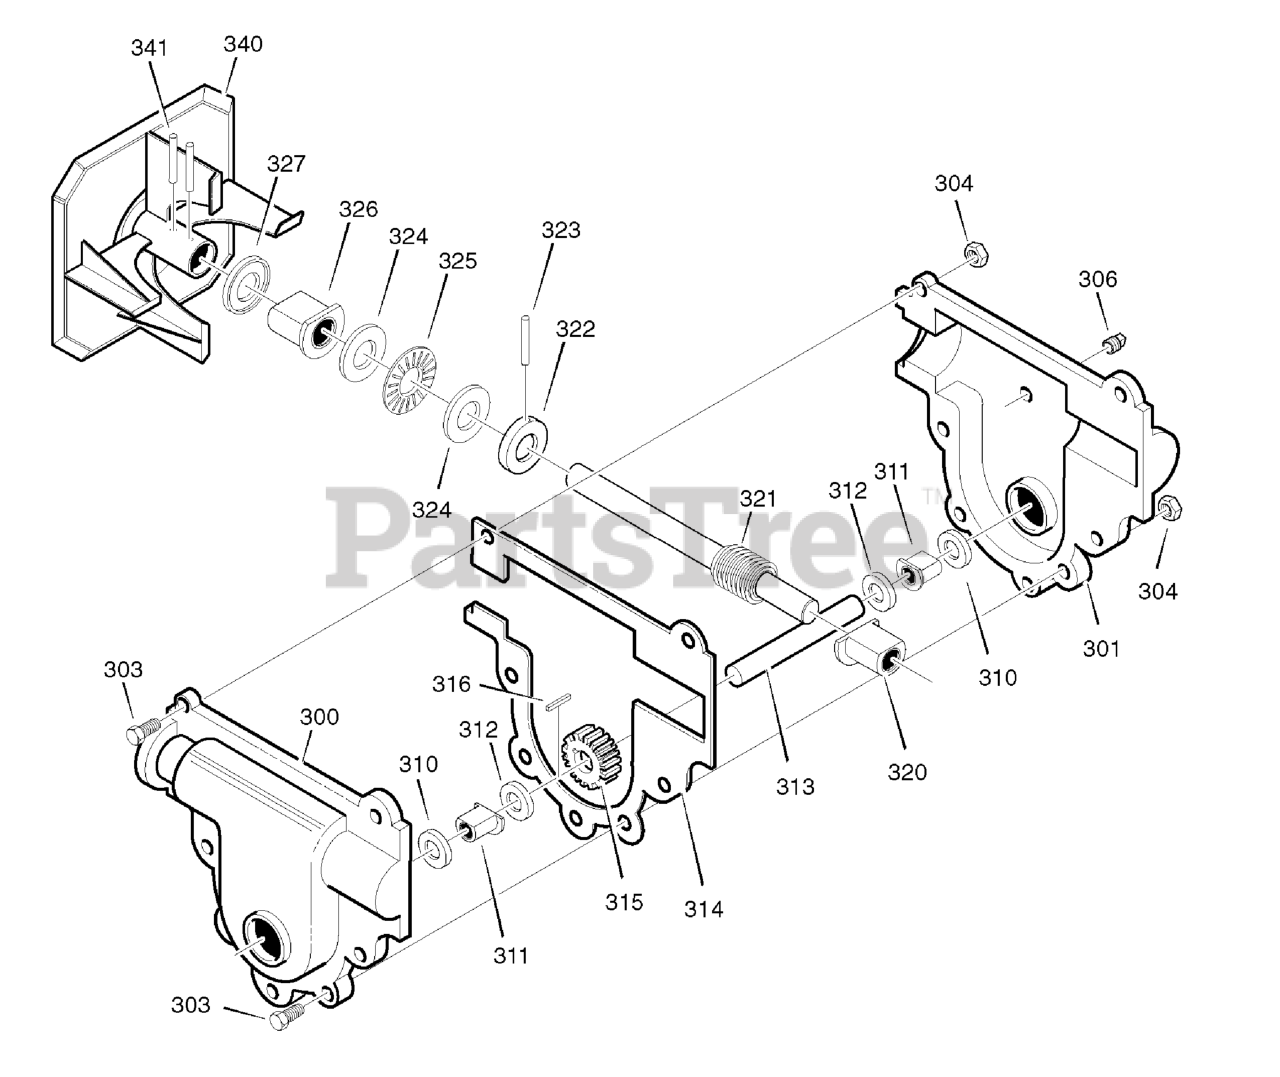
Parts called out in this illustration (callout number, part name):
300	CASE, GEAR, RH
301	CASE, GEAR, LH
303	SCREW,1/4-20X.75
304	NUT,1/4-20
306	SCREW, 3/8-16 x 0.50
310	SEAL, OIL
311	BEARING, FL
312	WASHER, FLAT
313	SHAFT, AUGER OUTPUT
314	GASKET, GEAR BOX
315	GEAR, WORM
316	KEY, WOODRUFF #61
320	BRNG, FL
321	SHAFT, AUGER INPUT (IMPELLER)
322	COLLAR, THRUST
323	PIN, SPRING
324	WASHER, FLAT
325	BRNG, ROLL
326	BRNG, FL
327	SEAL, OIL
340	IMPELLER
341	PIN, SPRING
